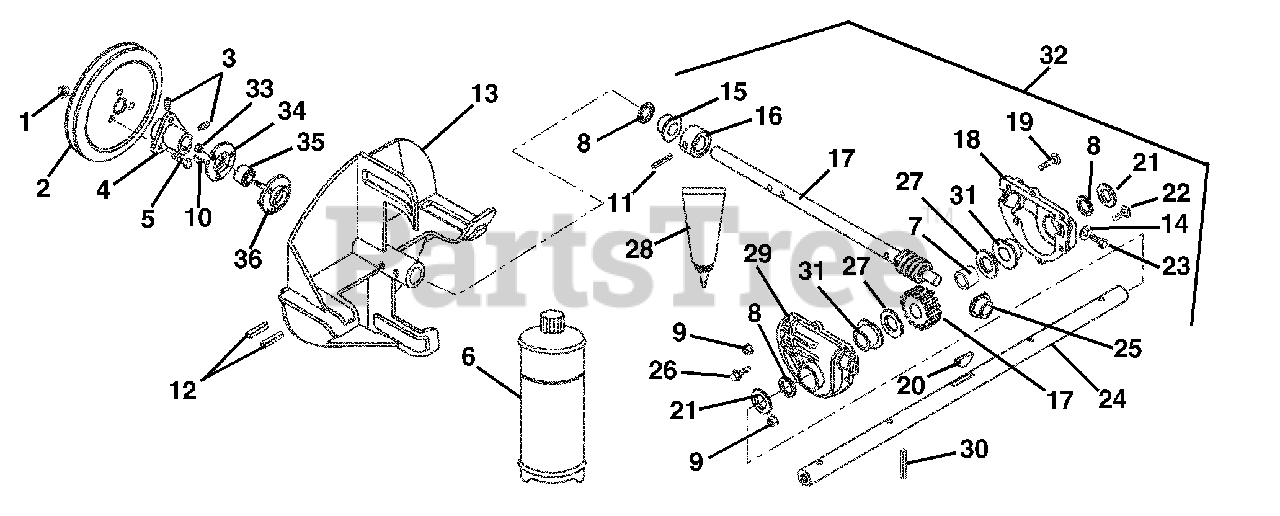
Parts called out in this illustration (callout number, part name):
1	@NUT-SPNLK-FLG .312-18 YWZC
2	PLY-V 8.50 X 1.25 3BLT
3	SCR-SET .31-18X.38 SKHCUPDL
4	HUB ASSEMBLY
5	BLT-SERRDHD SL .31-18X.75 YZ
6	ARIENS 16 OZ.BOTTLE OF L2 LUBE
7	BSHG-SLV .755X1.500X.442
8	SEAL-OIL .750X1.375X.250
9	@NUT-SPNLK-FLG .25-20 YWZC
10	KEY-WDRF .188X.875X.375 SAE11
11	PIN-GRV .188X1.25 TP A
12	PIN-ROLL .250X1.25
13	FAN - 12", BLACK
14	WSHR-FIBER .437X.656X.032
15	BSHG-FLG .750X1.000X.750X1.250
16	THRUST COLLAR
17	SHAFT AND WORM GEAR ASSEMBLY
18	CASE, GEAR-LH-LARGE BORE-ALUM.
19	@BLT-RDHDSQNK .25-20X1.25 G5YZ
20	KEY-WDRF .188X.625X.25 SAE 61
21	@WSHR-FL-STL.812X1.50X.135YWZC
22	@BLT-RDHDSQNK .25-20X1.00 G5YZ
23	@SCR-TAP .38-16X.50 HWH TR YWZ
24	SHAFT, RAKE - 24"
25	BSHG-FLG .502X1X.750
26	SCR-TAP 10-24X.75 HWH TR YWZC
27	WSHR-HDND-THRST .755X1.40X.062
28	LOCTITE 518 GASKET--6ML TUBE
29	CASE, GEAR-RH-LARGE BORE-ALUM.
30	PIN-GRV .313X1.44 TP C
31	BSHG-FLG .753X1.127X.500X1.501
32	GEAR CASE - 24" - ALUMINUM
33	@NUT-LK-CTR .25-20 YWZC
34	BEARING FLANGE
35	BRG-BALL .750X1.750X.50
36	BEARING FLANGE
